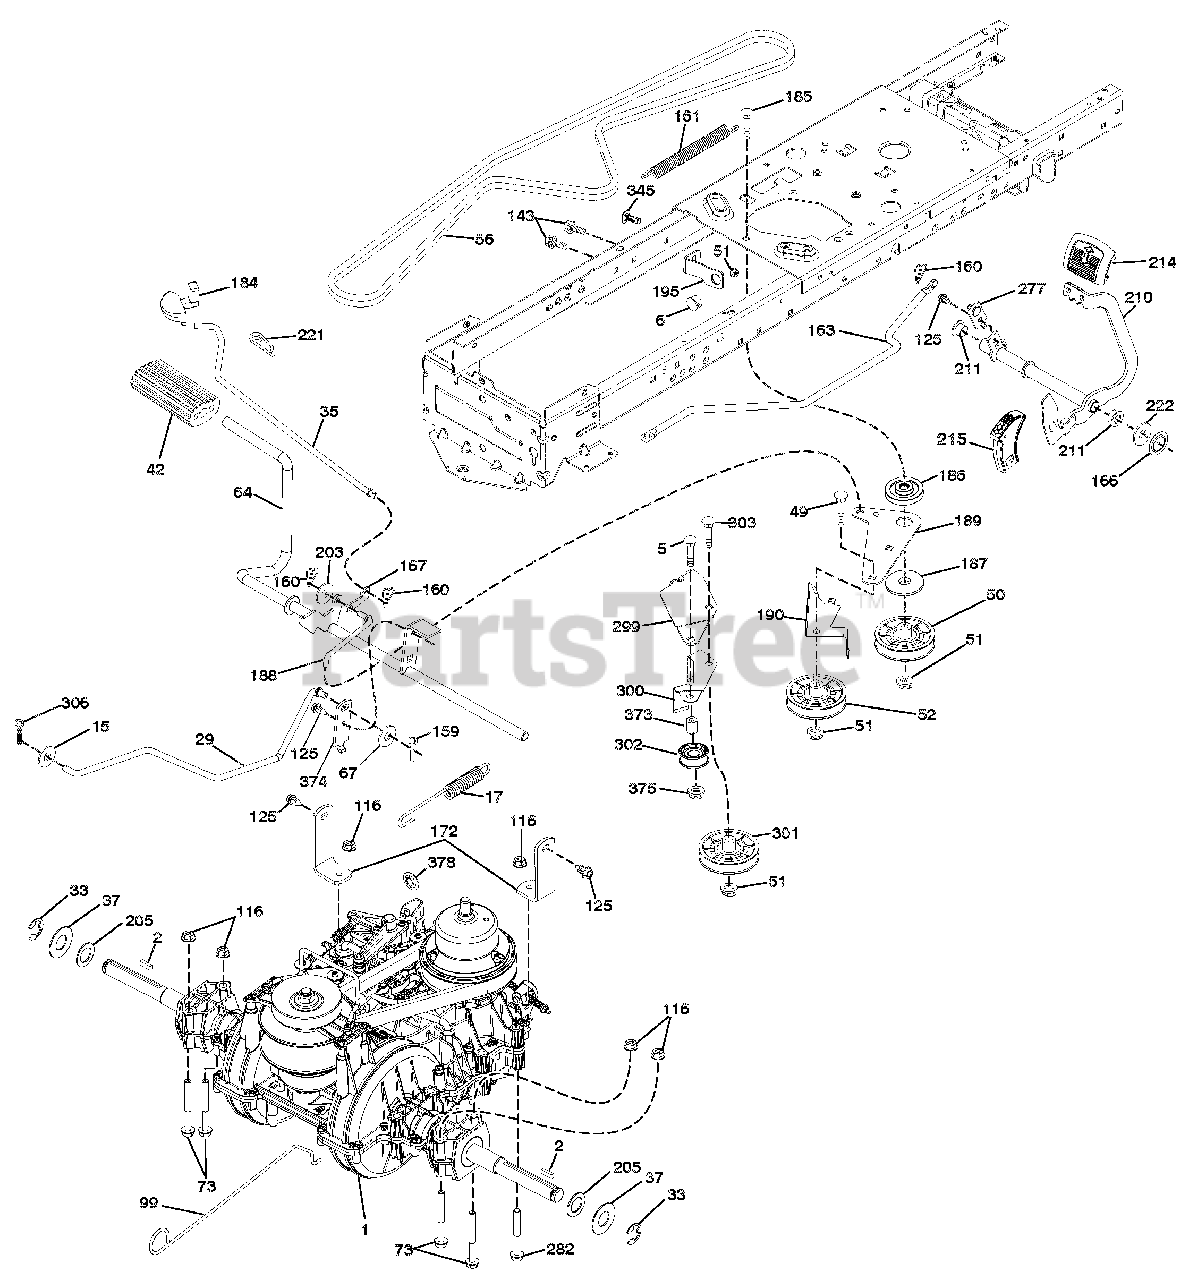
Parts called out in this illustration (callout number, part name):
1	TRANSMISSION, GENTRANS VATR
2	KEY.SQUARE.2.0 X .1845/.1865
5	BOLT.HEX.HS.3/8-16.UNCX2-1/4
6	Bushing Snap Nyl Blk Fuel Line
15	WASHER.13/32 X 13/16 X 16 GA.
17	SPRING BRAKE
29	ROD BRAKE
33	E-RING.#5133-75
35	ROD.BRAKE.PARKING.LT.TEX
37	WASHER.HARDEN..793 X 1.637X060
42	COVER PEDAL BLK ROUND
49	BOLT.RDHD.3/8-16UNCX1-3/4.GR5
50	IDLER.FLAT.910"OFFSET
51	Nut, Hex, Flangelock 3/8-16
52	IDLER.V-GROOVE.910"OFFSET
56	BELT.DRIVE.100.97"
64	SHAFT ASM. PEDAL BRAKE
67	Washer 13/32 x 13/16 x 12 Ga.
73	BOLT.HEX.FLGHD.5/16-18.GR.5
99	ROD.BYPASS
116	Nut, Lock Hex Flange 5/16-18 u
125	SCREW.5/16-18X3/4.SMGML.TAP/BL
143	SCREW.THDROL.5/16-18 X 1/2TYTT
159	PIN.COTTER.1/8 X 3/4.CAD.
160	RETAINER.CLIP(M).DIA.290
161	SPRING.RETURN.CLUTCH.6.75
163	ROD CONTROL PEDAL
166	NUT PUSH .625
167	LATCH.BRAKE.PARKING
172	STRAP TORQUE VARIATOR
184	HANDLE.PARKNG.BRAKE.LT.TEX.667
185	BOLT.RDHD.3/8-16UNC X2-3/4 GR5
186	SPACER.RETAINER
187	WASHER.13/32 X 2 X 10 GA.
188	LINK.CLUTCH.GROUND DRIVE
189	BELLCRANK.GROUNDRIVE.NSTG/NSTL
190	KEEPER.BELLCRANK.DRIVE.GROUND
195	BRACKET.BRAKE
203	Washer 11/32 x 11/16 x 16 Ga.
205	WASHER.25/32 X 1-5/8 X 16GA.
210	WELDMENT PEDAL
211	BEARING.NYLON.BLK..629 ID.
214	PAD PEDAL FORWARD
215	CAP PEDAL REVERSE
221	RETAINER.SPRING.CLIP.HANDLE
222	WASHER.21/32X1-1/4.10GA.N/PLTD
277	LINK ROCKER PEDAL
282	BOLT.HEX. 5/16-18 X 3 GR. 5
299	Bracket Mount Idler
300	Keeper Idler Rear
301	Pulley Idler V-Groove
302	PULLEY,IDLER.FLAT
303	Bolt RDHD SQNK 3/8-16 x 2-1/4
306	Pin Cotter 1/8 x 1 Cad
345	Bolt Rdhd Sht Sqnk 3/8-16 x 3/
373	SPACER.IDLER
374	ARM.BRAKE.CONTROL
375	Nut, Hex, Crownlock 3/8-16
378	NUT PUSH
